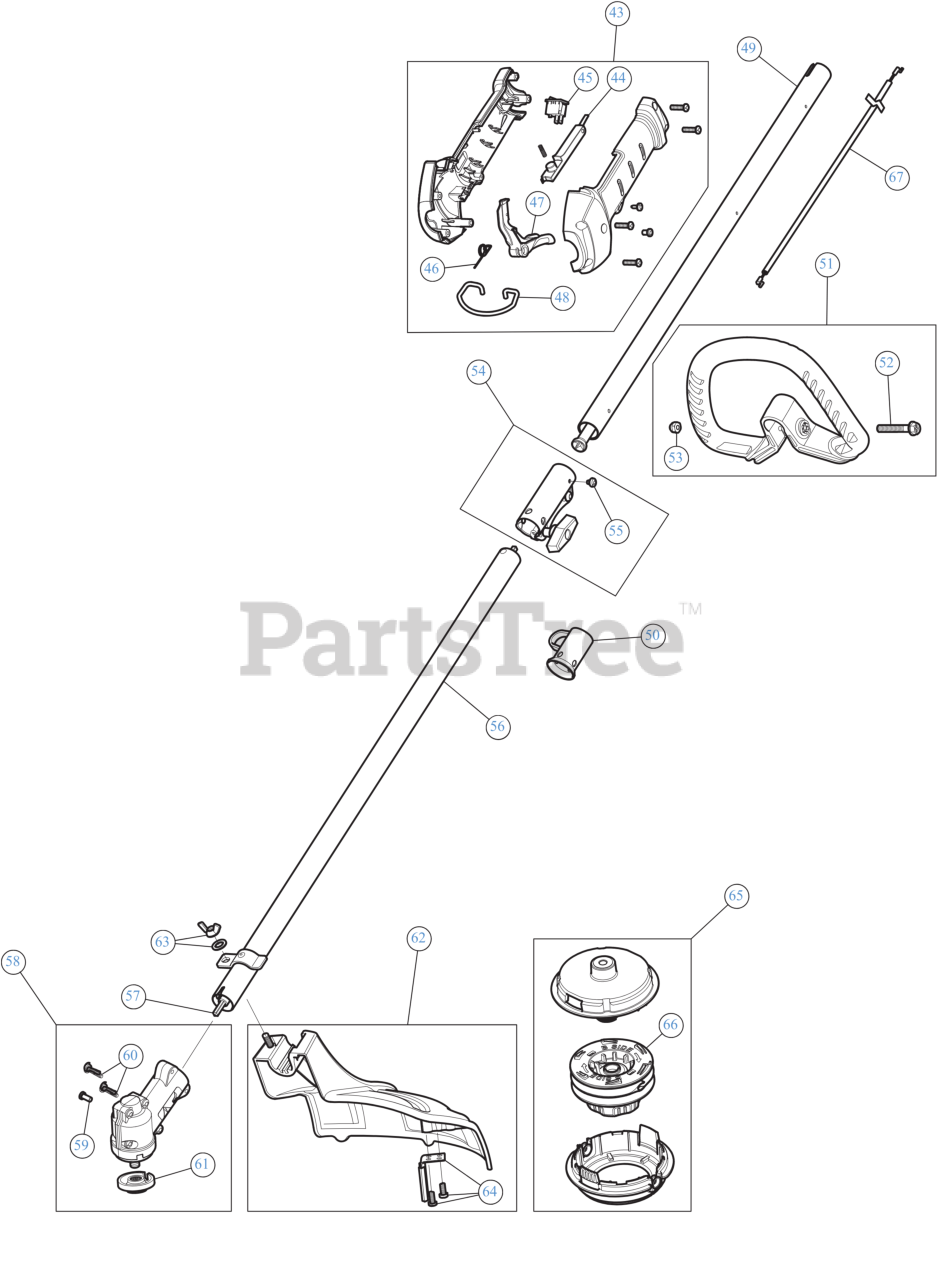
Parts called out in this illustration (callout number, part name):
43	THROTTLE GRIP ASM
44	LEVER LOCK OUT
45	SW, MOMENTARY ON/O
46	TRIGGER SPRING
47	THROTTLE TRIGGER
48	SHOULDER STRAP CLIP
49	DRIVE SHAFT ASSEMBLY UP
50	HANGER
51	HANDLE ASSEMBLY
52	BOLT 1/4-20X1 1/2
53	NUT 1/4-20 NYLOC
54	COUPLER ASSEMBLY
55	SCREW, 10-32X.250 TA
56	LOWER BOOM ASSEMBLY
57	LOWER DRIVE SHAFT
58	GEARBOX LCBC
59	SCREW, 8-32 x .312 P
60	SCREW #
61	CUTTING HEAD SPACER
62	GUARD/BLADE ASM
63	BLADE GUARD MOUNTING HARDWARE
64	BLADE ASSEMBLY W/HDW
65	CUTTING HEAD
66	BUMP KNOB
67	THROTTLE CABLE
